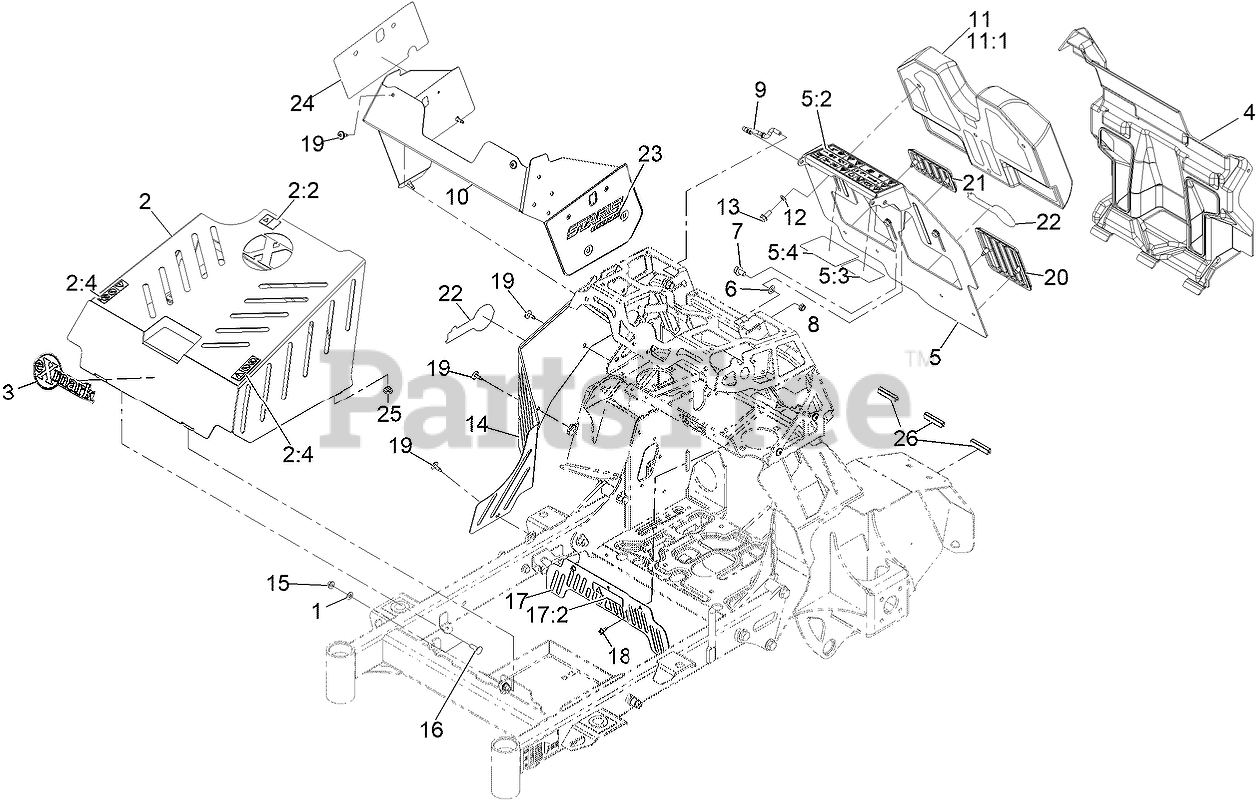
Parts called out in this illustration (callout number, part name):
1	SPACER-NYLON
2	ASM-COVER W DECALS
2:2	DECAL-WARNING
2:4	DECAL-NO STEP/RIDERS
3	DECAL, EXMARK LOGO
4	COVER-REAR STE
5	ASM, PAD BACKING W/ DECALS
5:2	DECAL-WARNING
5:3	DECAL-DRIVE RELEASE
5:4	DECAL-SERVICE AID SM
6	WASHER-THRUST
7	SCREW-HHF
9	ROD, PROP
10	SKIN, TOWER
11	PAD-THIGH
11:1	COVER, PAD
12	WASHER-BELLEVILLE
13	SCREW-HHF
14	COVER, RT SIDE
16	BOLT-CARR
17	ASM, BELT GUARD W/ DECAL
17:2	DECAL-WARNING
18	SCREW-HWH
19	SCREW, TORX
20	PAD, KNEE, LT
21	PAD, KNEE, RT
22	DECAL-EXMARK LOGO
23	DECAL-STARIS LOGO LT
24	Decal-Staris Logo Rt
26	STRIP-SEAL 2.13
